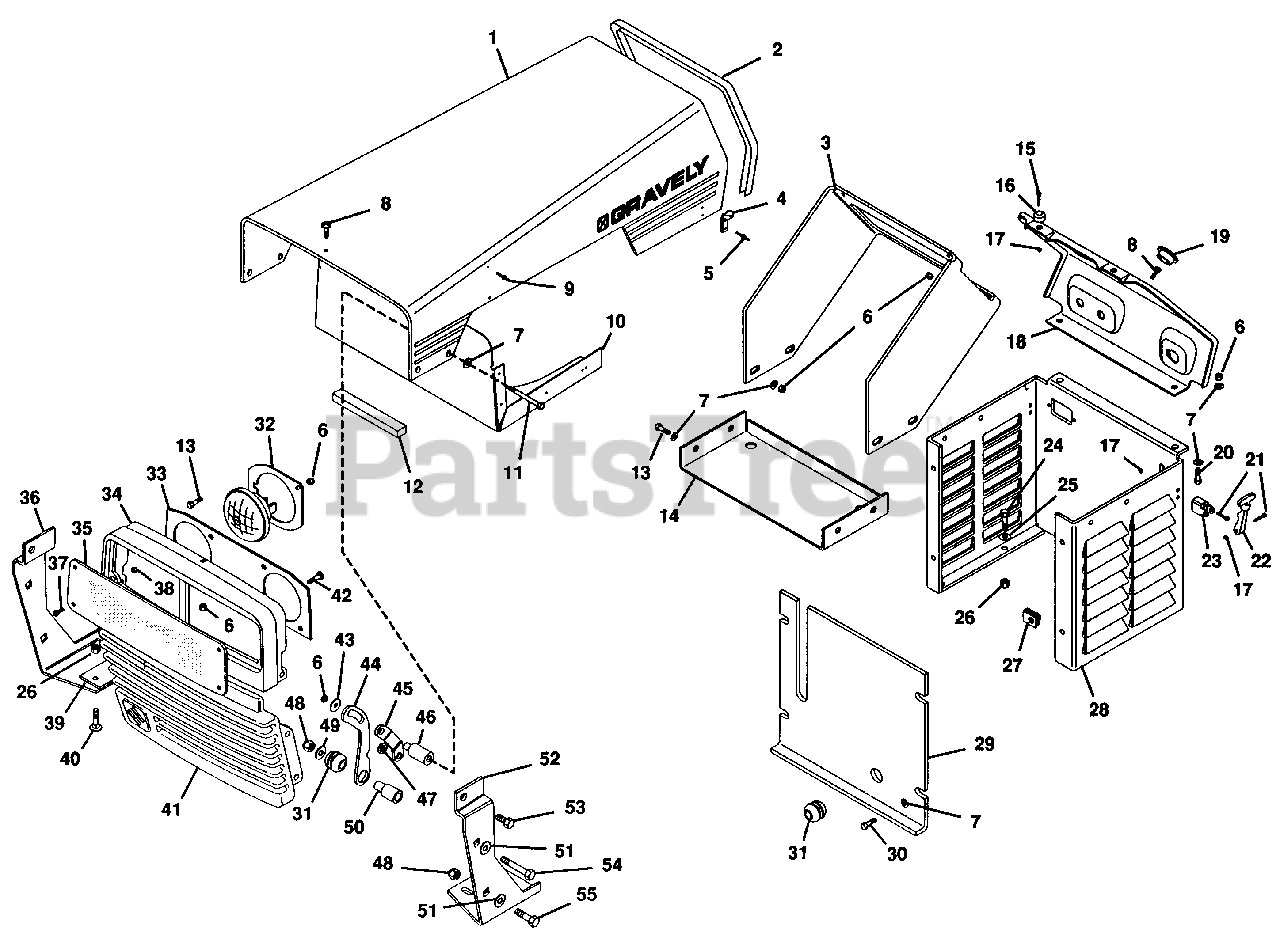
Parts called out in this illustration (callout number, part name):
1	Hood, GEM Silkscreen
2	Strip, Cowl
3	Bracket, Support
4	Keeper
5	Rivet, Dome Head
6	Nut, Lock 1/4-20
7	Washer, Flat .281 x .625 x .065
8	Screw, Mach. 1/4-20 PHD
9	Rivet, Pop .125 x .232
10	Baffle, Hood
11	Bolt, Hex 1/4-20 x 2.25
12	Pad, Baffle
13	Bolt, Hex 1/4-20 x 1.00
14	Tray, Battery
15	Screw, Mach. 6-32 x .625 PHD
16	Bumper
17	Nut, Mach. Lock 6-32
18	Panel, Silkscreen
19	Bush., Flg. .764 x 1.47 x .560 Ny.
20	Bolt, Hex 1/4-20 x .625
21	Screw, Mach. 6-32 x 1.0 PHCR
22	Latch, Flexible Draw
23	Block, Tie-Down
24	Bolt, Hex 5/16-18 x 1.00
25	Washer, Flat .344 x .688 x .065
26	Nut, Lock 5/16-18
27	Nut, Retainer
28	Panel, Silkscreen
29	Cover, Hydraulic Tank
30	Bolt, Hex 1/4-20 x .75
31	Grommet
32	Ring, Headlight Retainer
33	Panel, Headlight Reflector
34	Headlight, Bezel
35	Panel, Headlight Lense
36	Bracket(R.H.)
37	Screw, Mach. 10-24 x .75 PHD
38	Nut, Lock 10-24
39	Brace, Hood
40	Bolt, 5/16-18 x .875 Rd Hd Sq Nk
41	Casting, Grille
42	Screw, 1/4-20 x .50 Self Tapping
43	Washer, Flat .281 x 1 x .063
44	Hinge, Slotted
45	Hinge, Short L.H.
45	Hinge, Short R.H.
46	Pivot, Hood
47	Nut, Lock 3/8-16
48	Nut, Lock 3/8-16
49	Washer, Flat .438 x 1.000 x .083
50	Bush., Flg. .390 x .750 x 1.47 Stl.
51	Washer, Flat .406 x .812 x .065
52	Bracket, Grille
53	Bolt, Hex 3/8-16 x .75
54	Bolt, Hex 3/8-16 x 2.75
55	Bolt, Hex 3/8-16 x 1.25
NS	Decal, 12.5
NS	Decal, 14
